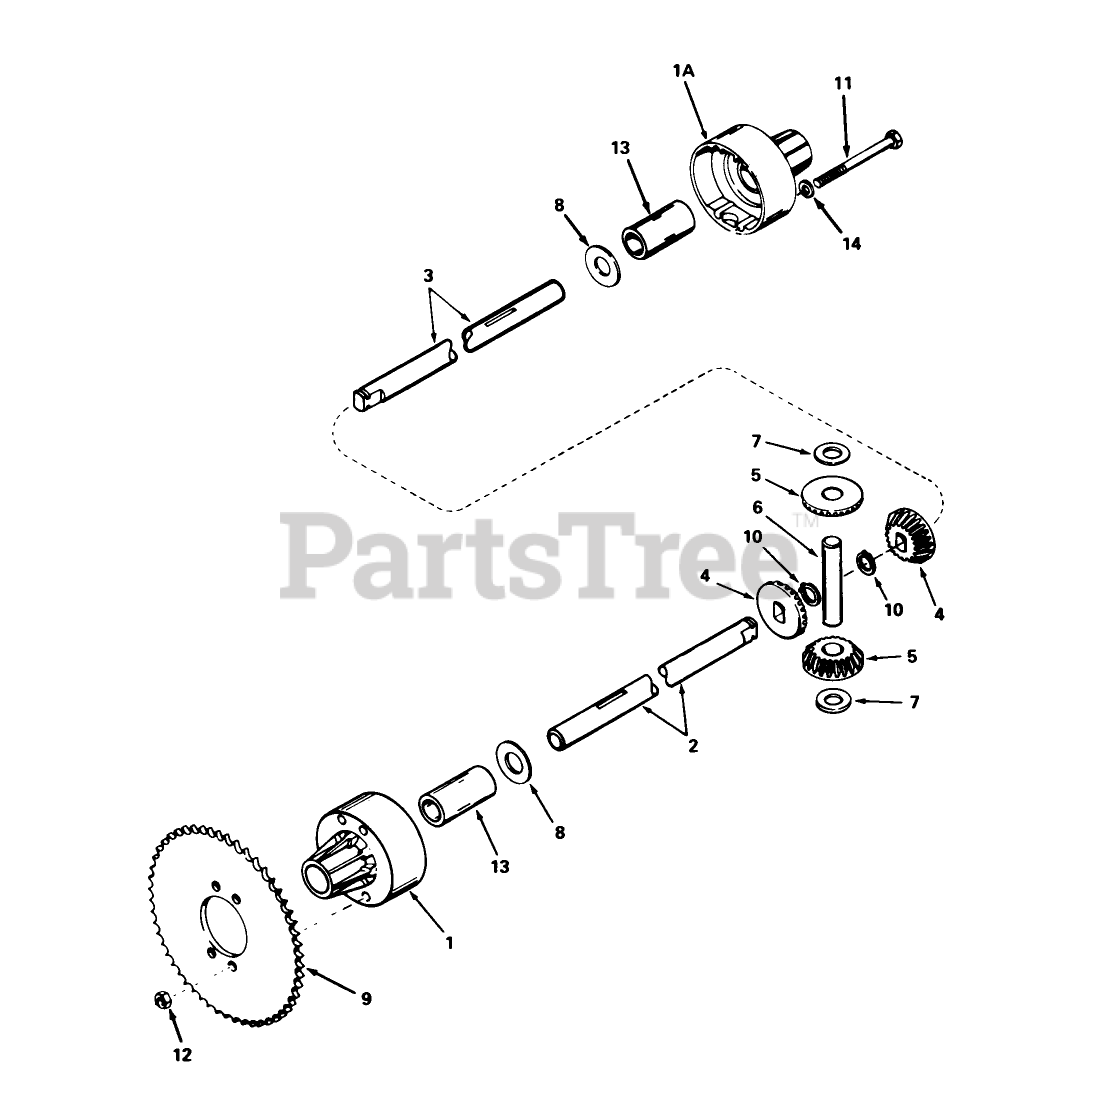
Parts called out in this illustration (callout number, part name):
1	Housing, Differential Carrier (Incl. Ref. #13)
1A	Housing, Differential Carrier (Incl. Ref. #13)
2	Axle (9-5/8" long)
3	Axle (18-1/4" long)
4	Bevel Gear
5	Gear Pinion
6	Pin Drive
7	Washer Thrust
8	Washer
10	Ring-Snap
11	Screw-Hex Hd.
12	Nut-Lock
13	Bushing
14	Washer
